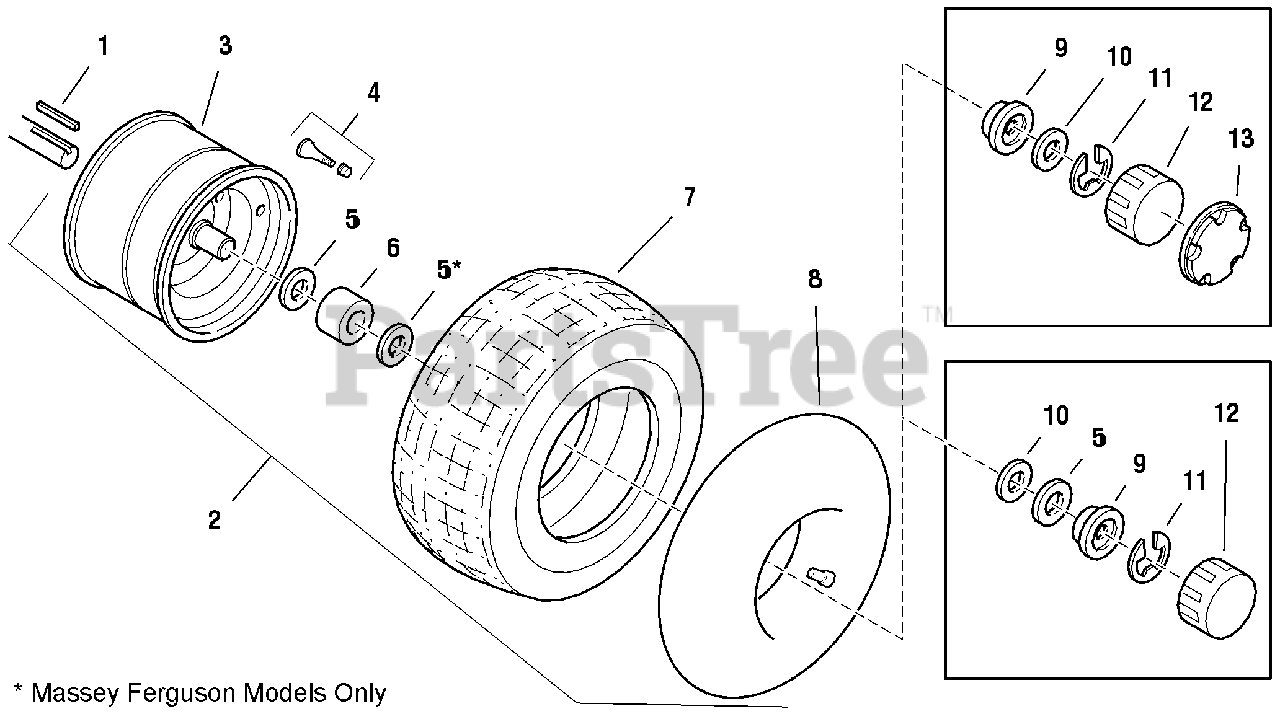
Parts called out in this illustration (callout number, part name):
1	KEY, Square, 3/16 x 3/16 x 1-1/2 long
2	REAR WHEEL & TIRE ASSY.
3	REAR WHEEL ASSY., Metallic Gray
4	VALVE STEM & CAP
5	WASHER, 3/4
6	SPACER
7	TIRE, Rear Wheel, 16 X 6.50-8
8	TUBE, Rear Wheel
9	RETAINER, Cap
10	WASHER, 3/4 I.D. x 1-1/16 O.D. x 1/16 Thk.
12	CAP, Threaded
13	HUB CAP, Scalloped, 8"
